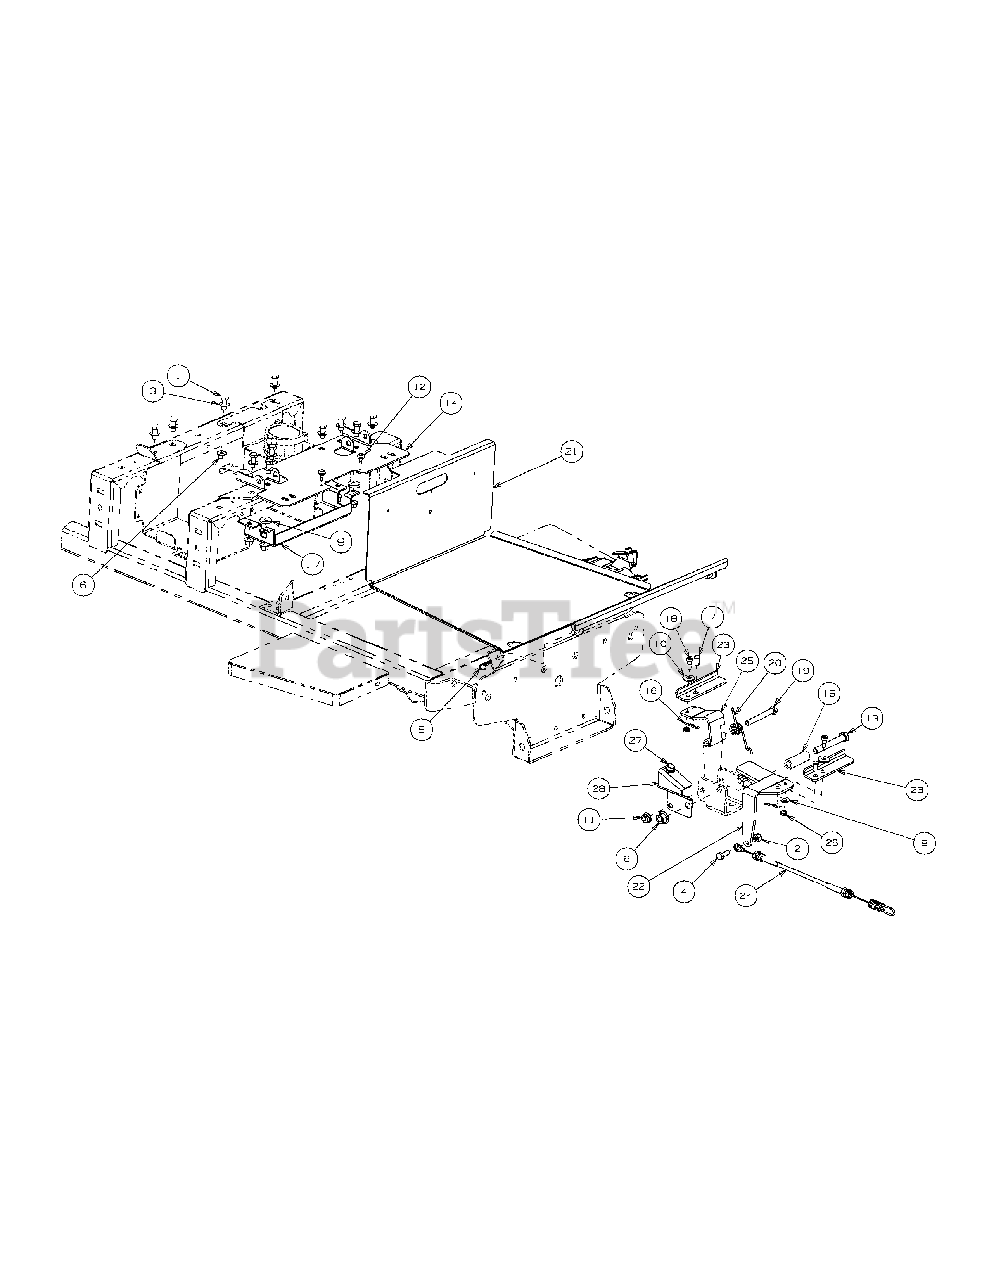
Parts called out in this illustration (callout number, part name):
1	Hex Cap Screw, 3/8-16 x 1.00
2	Lock Nut w/Nylon Insert
3	Flat Washer, 3/8
4	Hex Cap Screw, 1/4-20, .75
5	Hair Pin, 3/8" - 1/2"
6	Nut, Hex, Flange Lock, 3/8-16
7	Clevis Pin, 1/4 x 1/2, SS
8	Washer, 1/4, SS
9	Washer
10	Bell Washer, .265 x .75 x .062
11	Nut Lock, Hex Flange 5/16-18
12	Rubber Bumper, .62 OD x .22 Thick
13	Hex Cap Screw, 3/8-16 x 2.75
15	Spacer, .39ID x .63OD x 1.75LG
16	Cotter Pin, .072 x 1.12 Lg
17	Support, Seat Bracket
18	Shoulder Bolt, 1/4x1/4
19	Hex Cap Screw, 5/16-18 x 2.5
20	Deck Lift Spring, Left Hand
21	Floor Plate Assembly
22	Foot Pedal Latch Lever Assembly
23	Rate Plate Pad
24	Rate Plate On/Off Cable
25	Foot Pedal Latch Assembly
26	Nut, w/ Star Washer, 10-24
27	Light Indicator
28	Light Indicator Bracket
